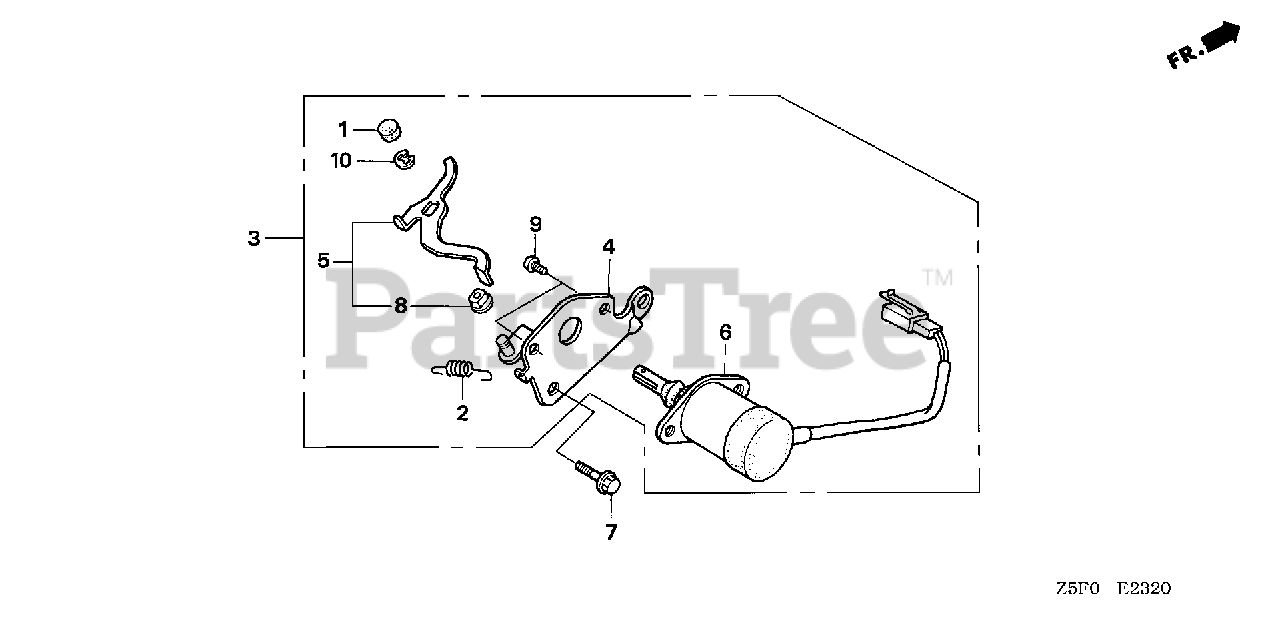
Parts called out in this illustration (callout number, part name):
1	CAP, CHOKE LEVER
2	SPRING, CHOKE RETURN
3	AUTO-THROTTLE ASSY.
4	STAY, SOLENOID THROTTLE
5	LEVER, SOLENOID THROTTLE
6	SOLENOID ASSY.
7	BOLT, FLANGE (6X12) (CT200)
8	BUSH, AUTO-THROTTLE LEVER
9	SCREW, PAN (5X8)
10	E-RING (4MM)
